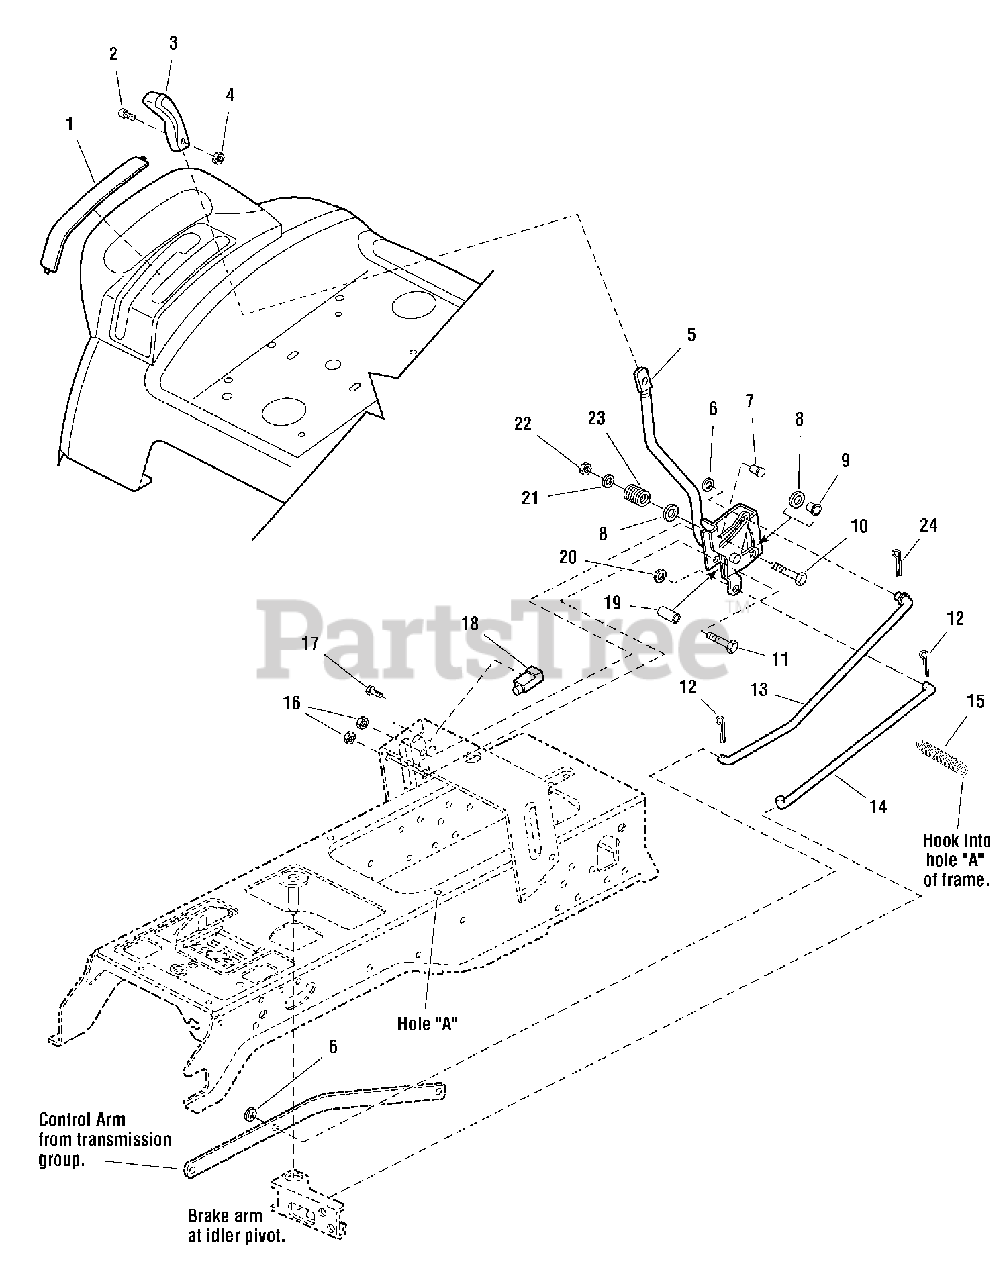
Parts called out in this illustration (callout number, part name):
1	COVER, w/Cruise Icon
2	SCREW, Torque Head Plus Socket Head, 1/4-20 x 7/8
3	KNOB, Cruise
4	NUT, Hex Lock ESNA Light, 1/4-20
5	LEVER & BRACKET ASSEMBLY, Cruise
6	WASHER, 3/8"
7	BOLT, Carriage, 5/16-18 x 3/4
8	WASHER, 1/2
9	SPACER, w/Flange, 11/32 x 15/32 x 3/4
10	BOLT, Carriage, 5/16-18 x 2-3/4
11	BOLT, Carriage, 5/16-18 x 2-1/4
12	PIN, Quick
13	ROD, Cruise
14	ROD, Return
15	SPRING, Cruise Return to Frame
16	NUT, Hex KEPS, 5/16-18
17	CAPSCREW, Hex Washer Head Plastite, 10-14 x 5/8
18	SWITCH, Interlock, Push, Neutral Start, Gray
19	SPACER, 11/32 x 5/8 x 1-13/32
20	WASHER, 5/16
21	WASHER, 5/16, Black
22	NUT, Hex Lock ESNA Light, 5/16-18
23	SPRING, Compression
24	PIN, Cotter
